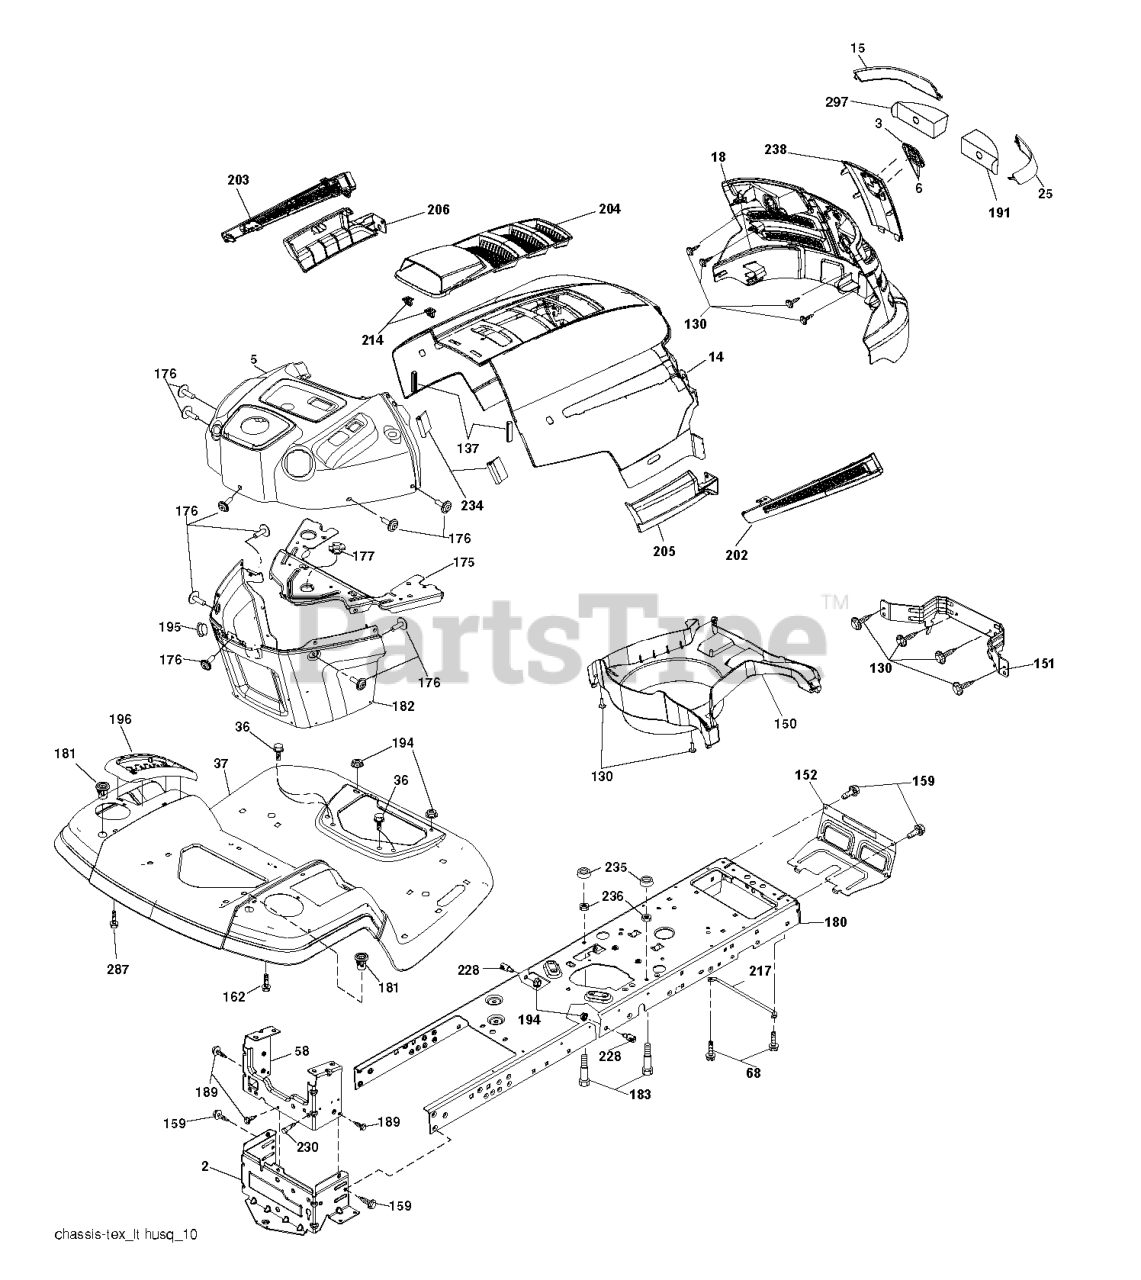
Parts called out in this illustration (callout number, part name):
2	DRAWBAR.LOWER.2PC.18/22
3	RP LOGO
5	DASH
14	HOOD
15	LENS.HUSQVARNA LT.LH
18	RP GRILLE/LENS ASM.
25	LENS.HUSQVARNA LT.RH
36	SCREW 5/16"
37	FENDER.TLT.FS.422
58	DRAWBAR UPPER 2PC SMALL FENDER
68	Screw 5/16-18 x 1/2 Hex, Self Tapping 5/16-18 x 1/2
130	SCREW.#10 X 0.750.BOS
137	BUMPER DASH
151	BRACKET PIVOT
152	SHIELD.BROWNING/DEBRIS
159	SCREW, 3/8-16X3/4
175	CROSSMEMBER
176	SCREW.#10-24X5/8.RN.QU
177	BUSHING STEERING
180	CHASSIS.STAMPING.LT/GT
181	BUSHING.MNT.FEND.CRGO.
182	DASH.LOWER.PREDATOR LT
183	BOLT.5/16-18X1-1/4 FULL.THREAD
189	SCREW
191	INSERT REFLECTIVE
194	NUT LOCK HEX FLANGE 5/16-18
195	PLUG DASH
196	RP CONSOLE.ASM.DECKLFT.GR/RBT.
199	PLATE.DECK.LIFT.HUSQ.LT
202	VENT SIDE HOOD RH
203	VENT SIDE HOOD LH
204	VENT TOP HOOD
205	SKIRT SIDE RH
206	SKIRT SIDE LH
214	CLIP.RETAINER.TINNER.
217	ROD.PIVOT.HOOD
228	STUD.FASTNER.W/ANTI-ROTATE
230	SHOULDER BOLT 5/16-18TT
234	BUMPER.HOOD.TEX.HUSQVARNA
235	SPACER FENDER
236	NUT.CENTERLOCK.5/16-
238	TRIM
287	SCREW 1/4X20
297	INSERT.REFLECTIVE.RH.
